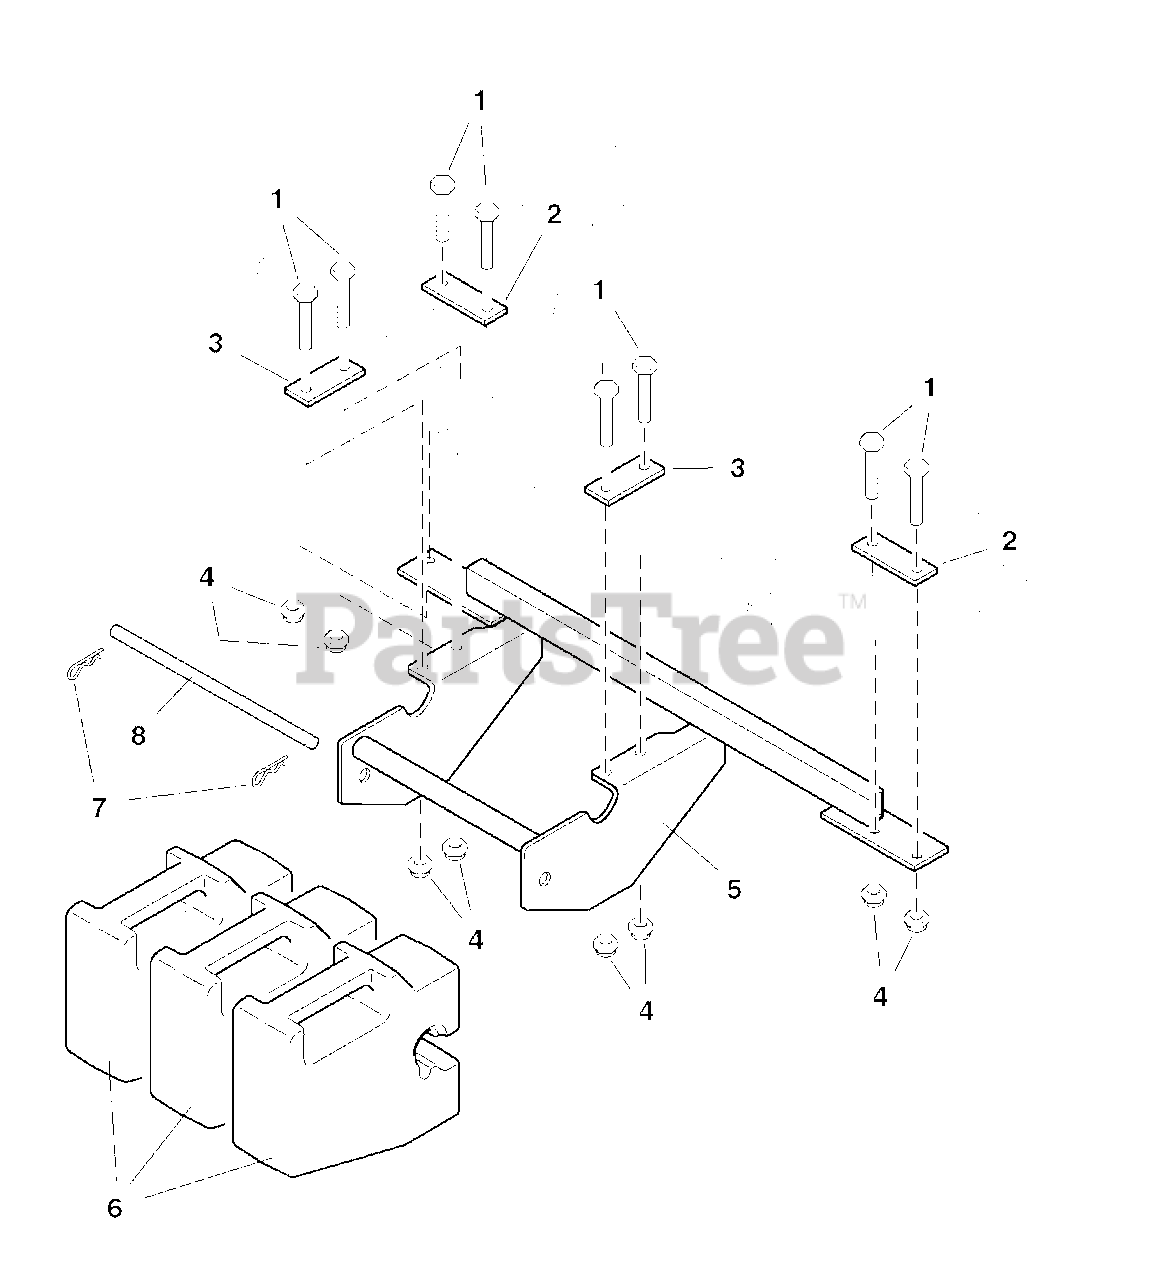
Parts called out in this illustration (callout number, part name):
1	CAPSCREW, Hex Hd, 3/8-16 x 3
2	BAR CLAMP - Side
3	BAR CLAMP - Front
4	NUT, Hex, Nylon Lock, 3/8-16
5	WEIGHT MOUNT
6	WEIGHT, 50 lbs.
7	HAIRPIN CLIP
8	RETAINER ROD
